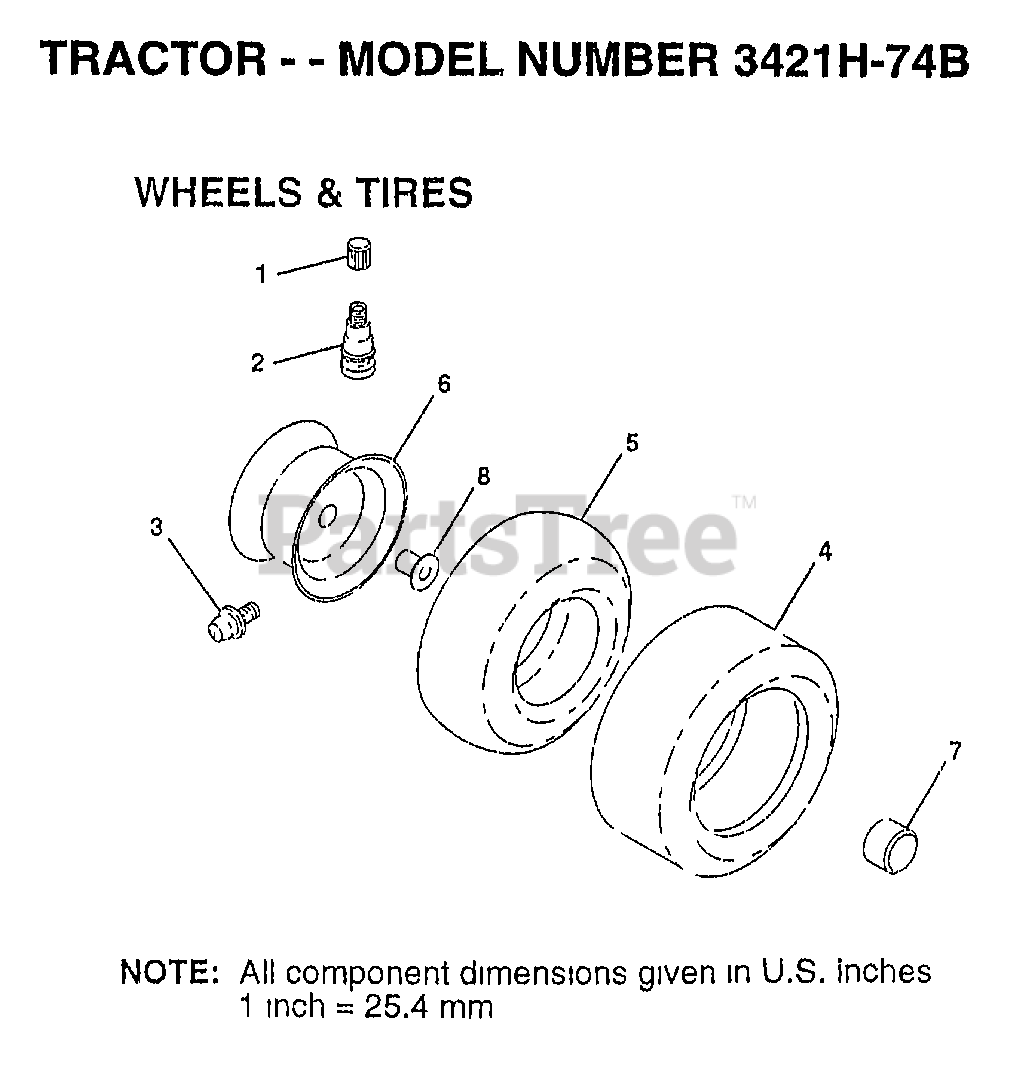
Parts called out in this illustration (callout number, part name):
1	VALVE CAP
2	VALVE STEM LT
3	FITTING LT
4A	TIRE.20X8-8
5	TUBE.5.3/4.5/6
5A	TUBE.18X9.5-8
6	"RIM,FRT T"
6A	"RIM 8"""
7	HUB CAP
8	"FLANGE, BEARING"
